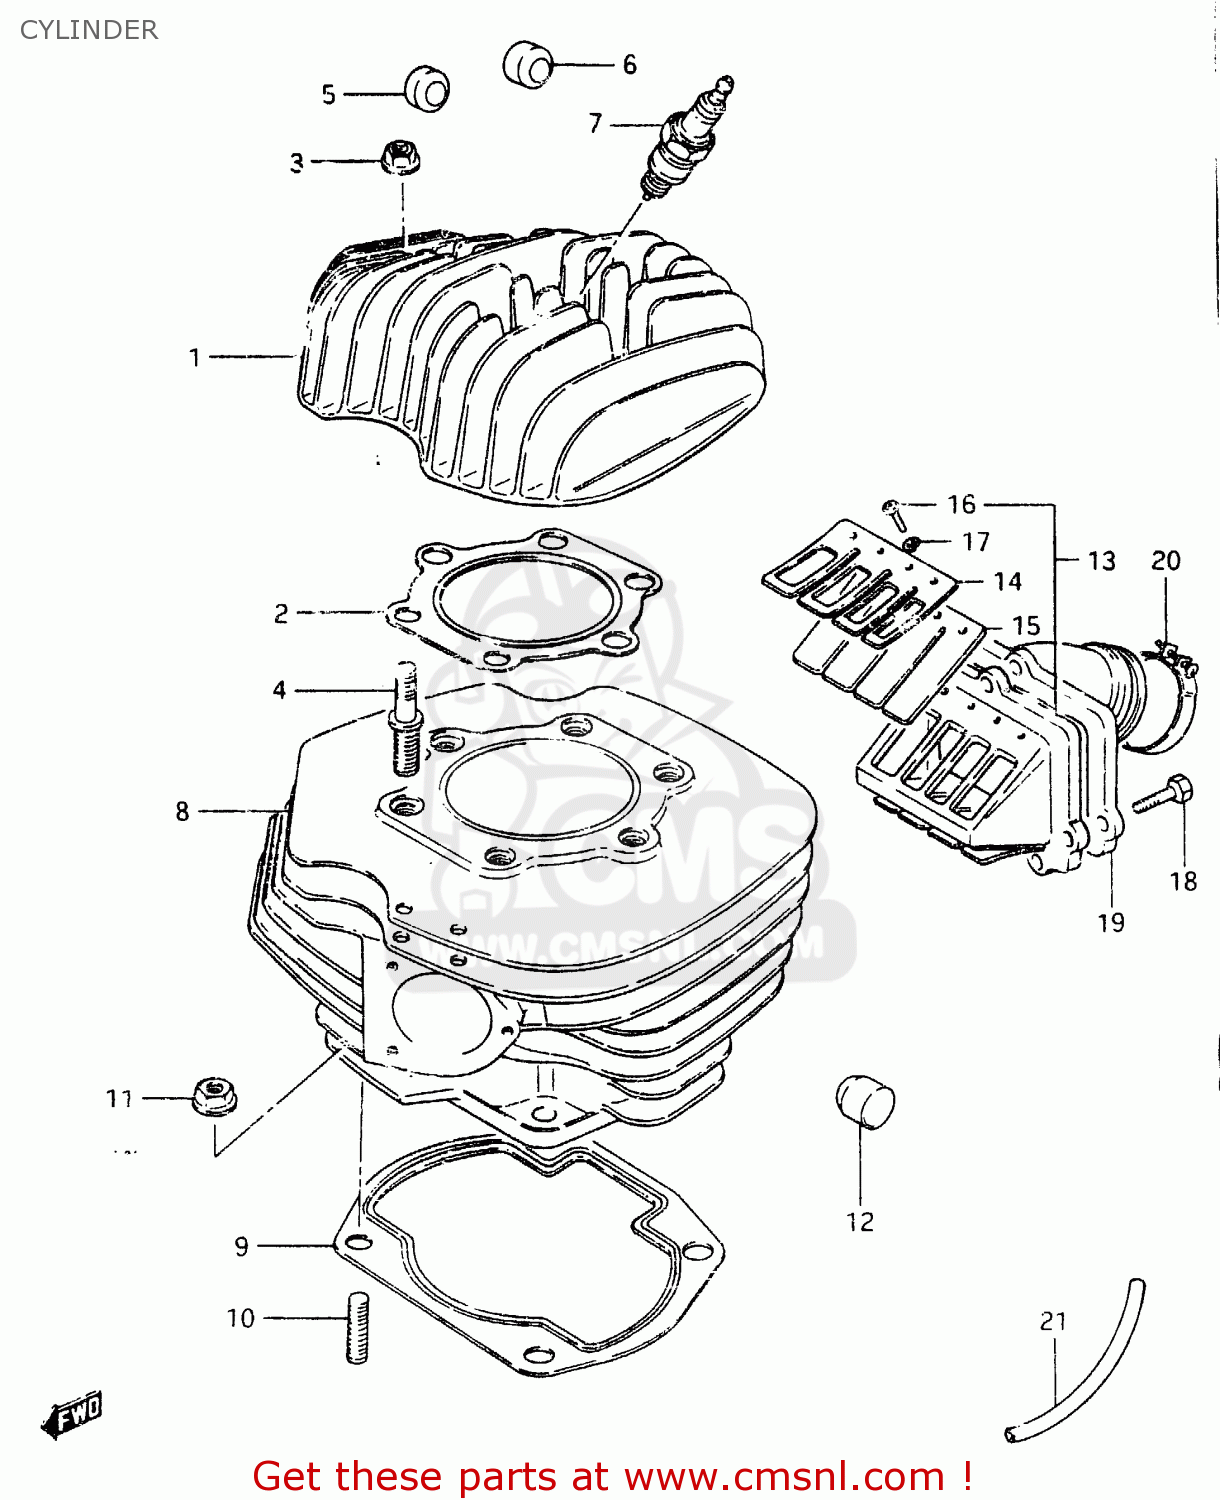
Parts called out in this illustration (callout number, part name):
1	HEAD,CYLINDER
2	GASKET,CYLINDER HEAD (NAS)
3	NUT
4	BOLT,STUD
5	PAD,CYLINDER
6	PAD,CYLINDER HEAD
7	PLUG,SPARK(NGK B-8EN)
8	CYLINDER
9	GASKET,CYLINDER (MCA)
10	STUD 10X30
11	NUT
12	PAD,CYLINDER HEAD
13	VALVE ASSEMBLY,REED
14	STOPPER,REED VALVE
15	VALVE,REED
16	SCREW
17	LOCK WASHER
18	BOLT
19	PIPE,INTAKE
20	CLAMP
21	HOSE
